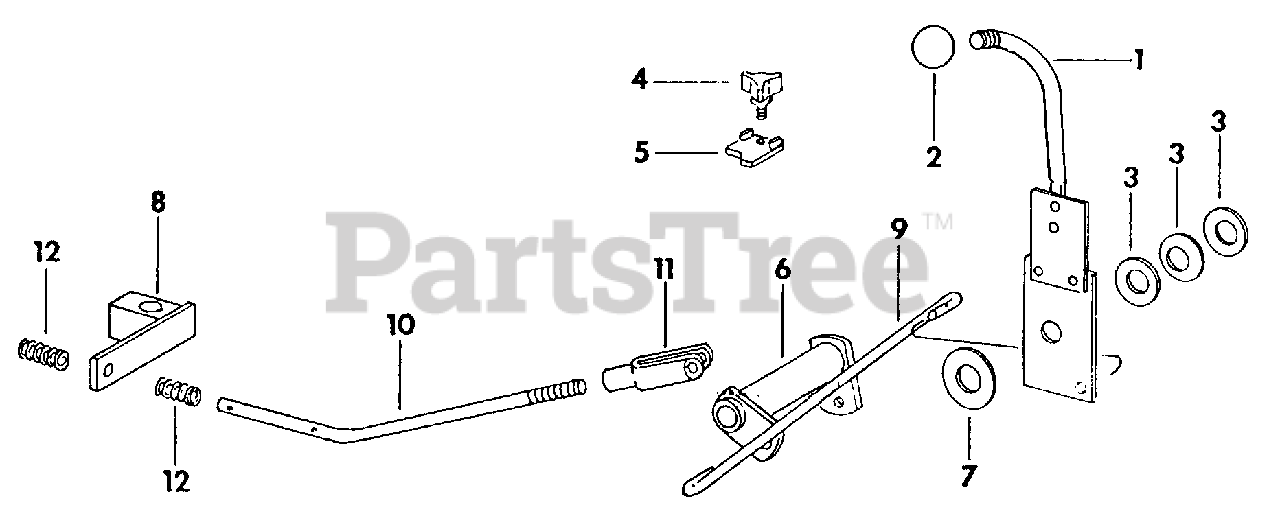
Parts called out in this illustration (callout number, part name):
1	Lever Assy, Speed Control
2	Knob, Shifter
3	Spring, Belleville
4	Knob, Fluted
5	Stop, Handle Detent
6	Rockshaft Assy
7	Washer, Frictional Disc
8	Arm Assy, Control Shaft
9	Rod, Control
10	Rod, Control Rear
11	Clevis, 5/16-24 Adj Rod End
12	Spring, Compression
